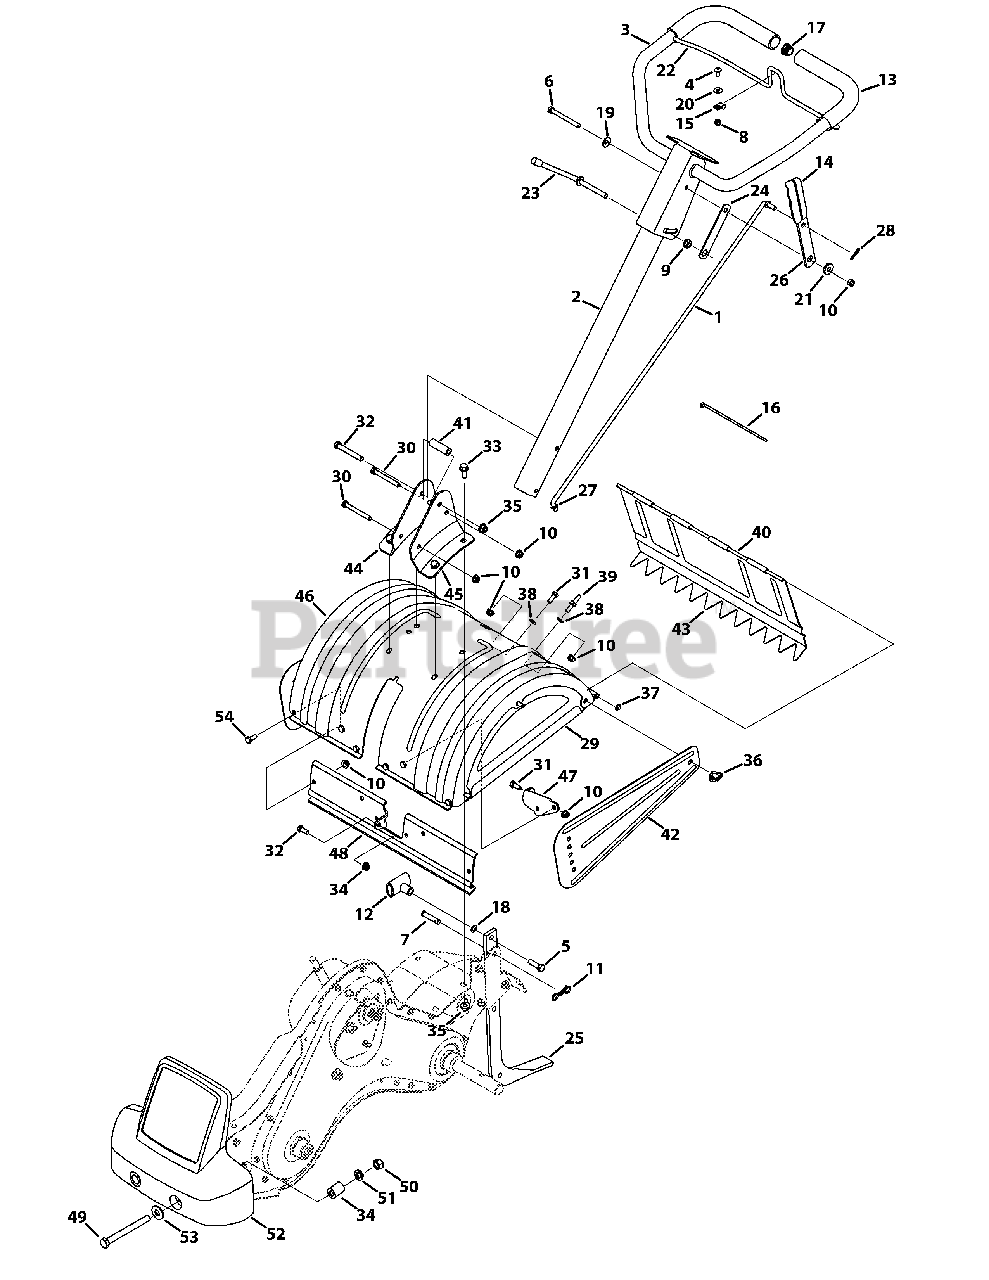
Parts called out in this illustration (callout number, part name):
1	Shift Rod
2	Lower Handle Tube Assembly
3	Upper Handle Assembly
4	Screw, 1/4-20 x 0.625
5	Hex Screw, 3/8-16:1.25
6	Hex Screw, 5/16-18 x 3.25
7	Clevis Pin, .375 X 1.75
8	Hex Lock Nut, 1/4-20
9	Flange Lock Nut, 3/8-24
10	Hex Lock Nut, 5/16-18
11	Cotter Pin
12	Small Tee Knob
13	Foam Grip, .970 x 11.0
14	Grip, .1875 x 1.00
15	Battery Clamp, 5/16
16	Cable Tie, 8.5
17	End Plug
18	Flat Washer, .385 x .620 x .033
19	Bell Washer, .340 x .872 x .060
20	Flat Washer, .260 x .720 x .060
21	Spacer, .50 x .190 x .360
22	Clutch Bail
23	Handle Adjustment Crank
24	Hex Nut Retainer Bracket
25	Tiller Depth Control
26	Shaft Rod Lever
27	Washer, .33 x .87 x .125
28	Cotter Pin, .072 x 1.12
29	End Cover Assembly
30	Hex Screw, 5/16-18 x 2.75
31	Hex Screw, 5/16-18 x 1.00
32	Hex Screw, 3/8-16 x 2.75
33	Hex Flange, 3/8-16 x .875
34	Hub, .636 x 1.00 x .94
35	Flange Lock Nut, 3/8-16
36	Wing Nut, 5/16-18
37	Speed Nut Cap, 1/4
38	Flat Washer, .344 x .62 x .033
39	Screw, Hex, 5/16-18 x .75
40	Tiller Flap Rod
41	Spacer, .322 x .625 x 2.00
42	Side Shield
43	Rear Tine Shield
44	RH Handle Mount Bracket
45	LH Handle Mount Bracket
46	Tine Shield
47	FRT Tine Shield Bracket
48	FRT Tine Shield Spacer Bracket
49	Hex Screw, 1/2-20 x 5.50
50	Hex Lock Nut, 1/2-20
51	Flat Washer, 1/2 x 1.25 x .10
52	Counterweight
